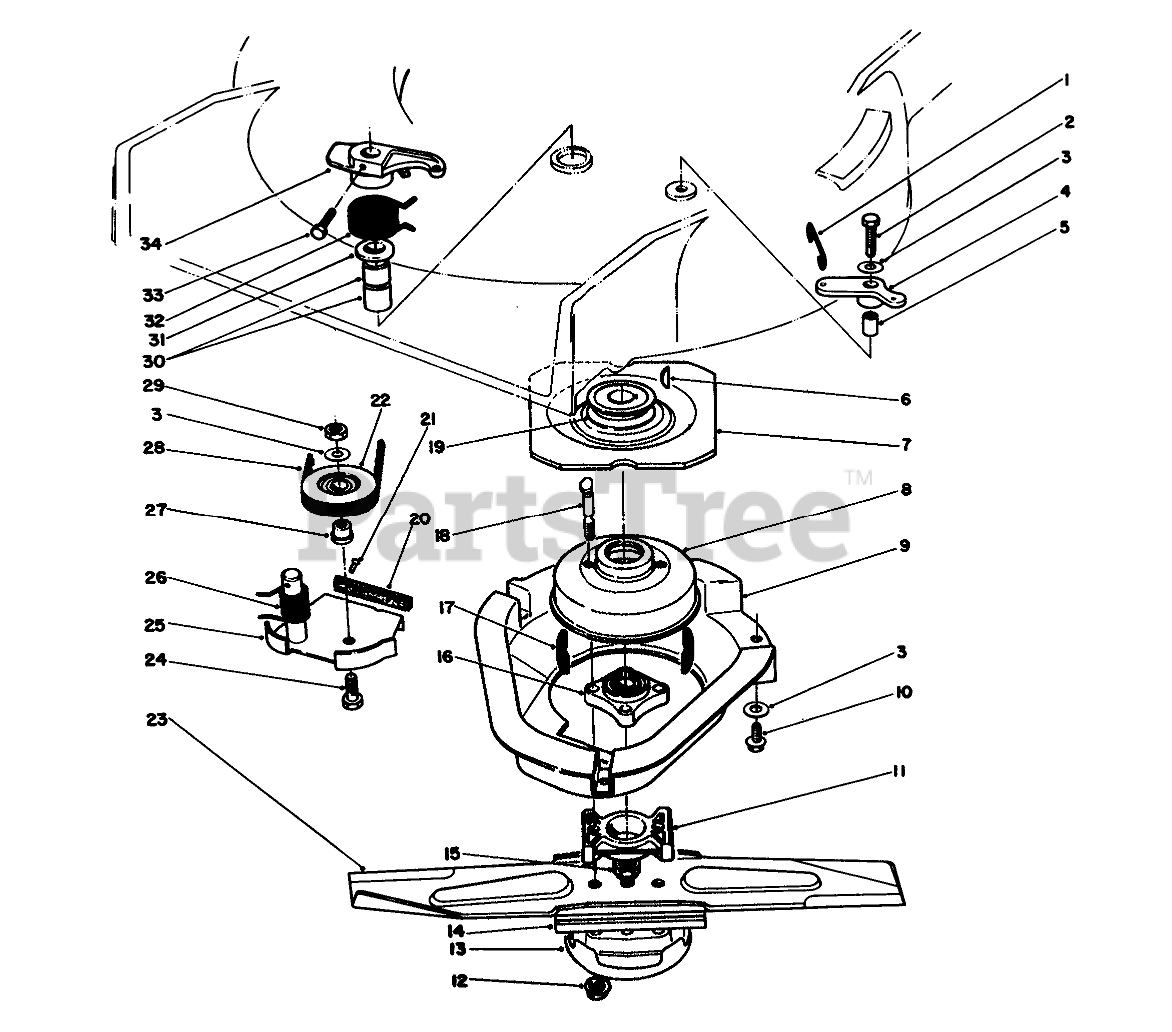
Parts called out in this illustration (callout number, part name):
1	LINK-CONTROL
2	SCREW-HH
3	WASHER-PLAIN
4	BELLCRANK
5	SLEEVE-BELLCRANK
6	KEY-WOODRUFF
7	Flywheel
8	Drum-Brake
9	SHIELD BBC
10	SCREW-HWHTF
11	SPACER-BLADE
12	NUT-LOCK
13	CUP-SCALP, ANTI
14	Stiffener
15	NUT-LOCK, NI
16	HUB ASM
17	DAMPENER-VIBRATION
18	BOLT-BLADE
19	PULLEY
20	Pad-Brake
21	.185 DIA X .375 RT +
22	PULLEY-IDLER
23	Blade
24	SCREW-HH
25	Brake Plate (Incl. Ref. #20 & 21)
26	SPRING-TORSION
27	HUB-PULLEY, IDLER
28	V-BELT
29	NUT-LOCK, NI
30	BEARING
31	WASHER
32	SPRING-TORSION
33	SCREW-HH
34	LEVER
